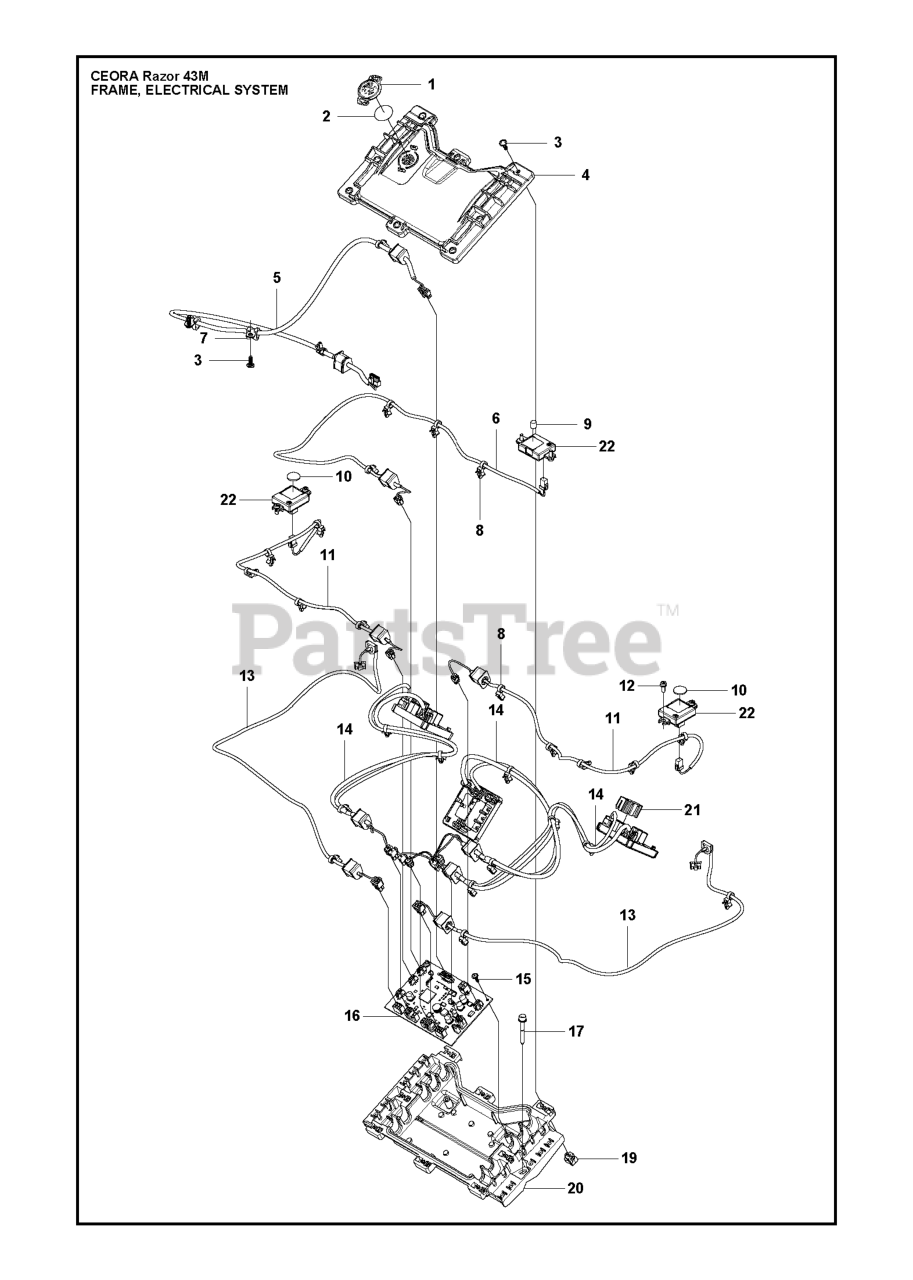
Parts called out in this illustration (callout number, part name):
1	COVER
2	KIT AIR FILTER KIT 305 - 10 PC
3	SCREW ITXPANT
4	COVER MAIN BORD COVER WITH DIS
5	WIRING ASSY CONTROLBOARD FRONT
6	WIRING ASSY MAGNETIC & LOOP SE
7	CABLE HOLDER
8	TIE WRAP CABLE TIE W ARROW MOU
9	MAGNET NEODYMIUM A8 L10
10	MAGNET D20X2
11	WIRING ASSY MAGNETIC & LOOP SE
12	SCREW
13	WIRING ASSY HEIGHT ADJUSTMENT
14	CONTROL UNIT G4.B
15	SCREW 14MM
16	PRINTED CIRCUIT ASSY PCBA CONT
17	SCREW ISO 10644 M6X45-10.9-S1
19	INSERT SCREW BLOCK
20	BASE ELECTRONICBOX MAINBOARD
21	COVER COVER G4B
22	HOUSING ASSY MAGNETIC SENSOR
